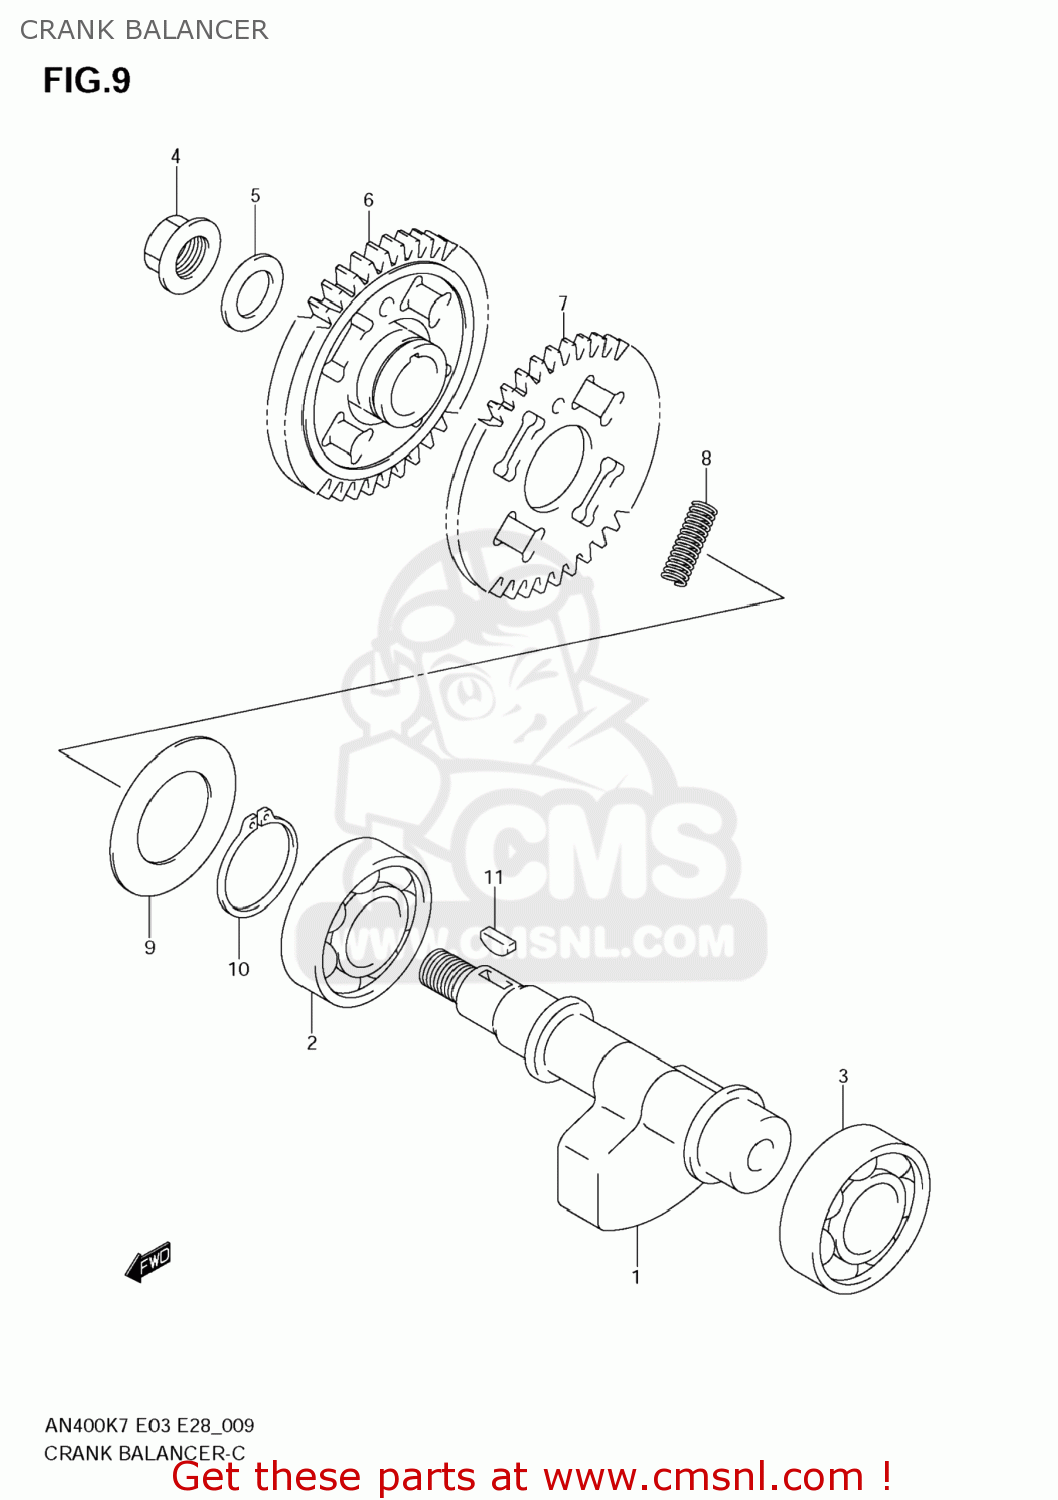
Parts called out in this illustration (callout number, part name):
1	BALANCER,CRANK
2	BEARING(20X47X14)
3	BEARING(22X50X14)
4	NUT
5	WASHER
6	GEAR,CRANK BAL DRIVEN NO.1
7	GEAR,CRANK BAL DRIVEN NO.2
8	SPRING
9	WASHER
10	CIRCLIP
11	KEY
